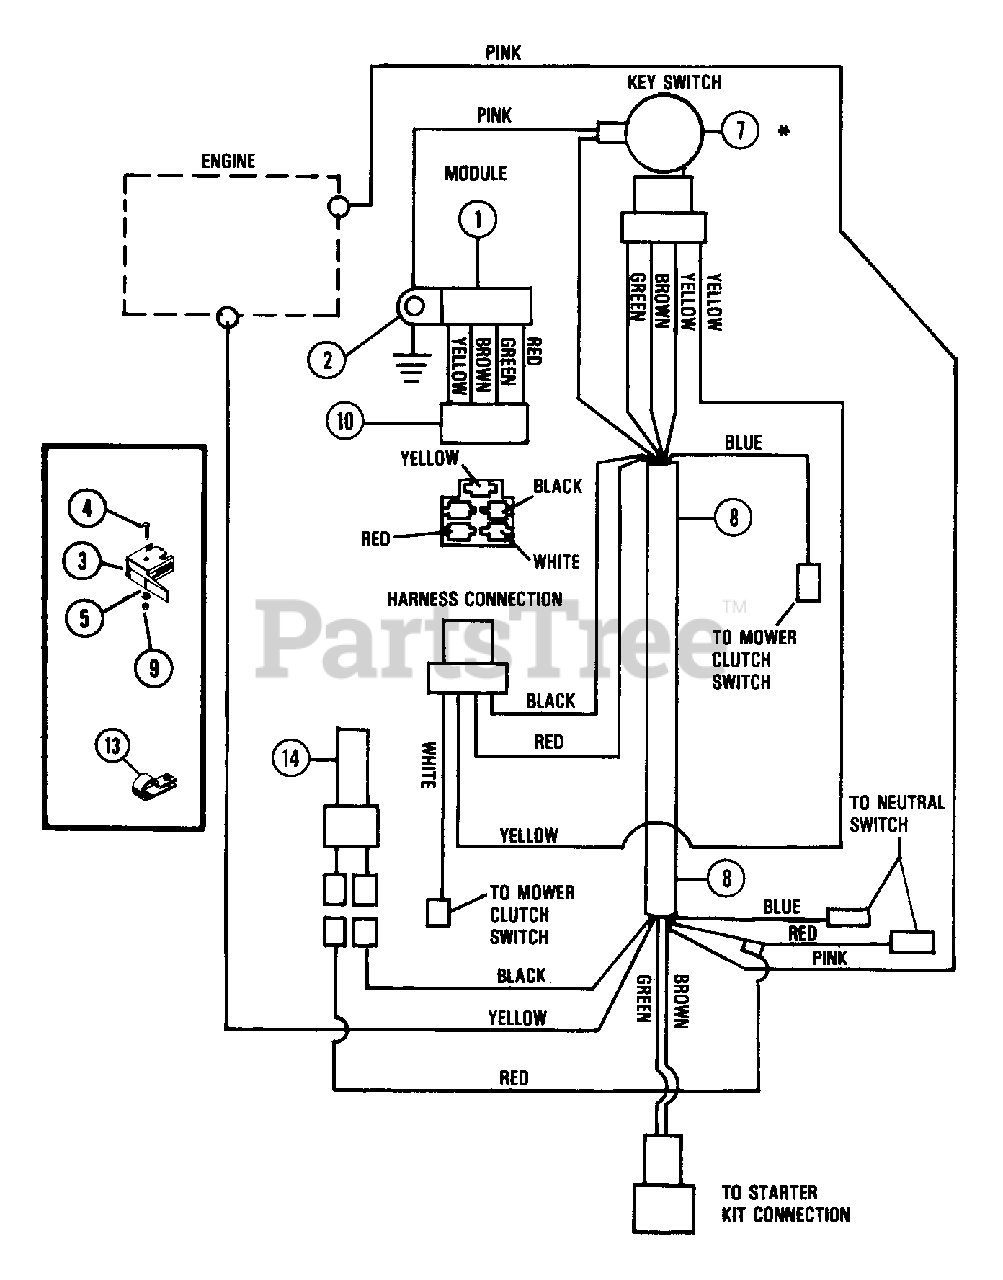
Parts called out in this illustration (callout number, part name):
1	MODULE
2	SCR-TAP 10-12X.50 CRPH PL A
3	SWITCH INTERLOCK
4	SCR-MCH 10-24X1.00 SLRH PL
5	WSHR-LK 10X.047 MED PL
6	NUT .625-32 ALUM
7	SWITCH & KEY SET ASSEMBLY
8	WIRE HARNESS
9	NUT-HEX 10-24 PL
10	CONNECTOR
11	KEYS
12	WSHR-LK-INT .625X.045 PL
14	SWITCH SEAT
